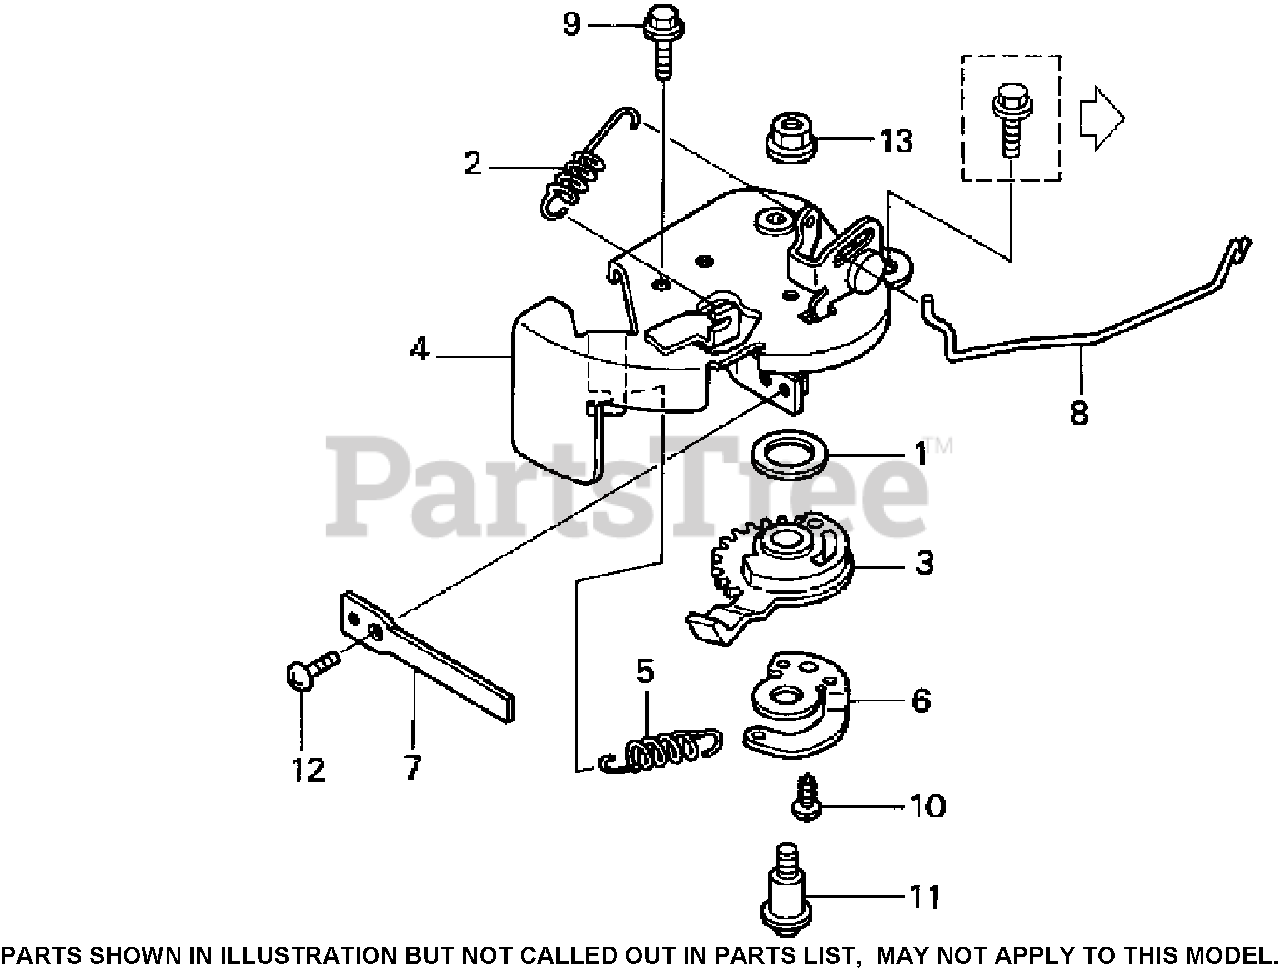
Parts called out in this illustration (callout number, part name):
1	SEAL-LEVER, CHOKE
2	SPRING-RETURN, CABLE
3	LEVER-CHOKE
4	BASE-CHOKE
5	SPRING-LEVER, CHOKE
6	HOOK-SPRING, CHOKE
7	PLATE-CHOKE
8	ROD-STOP
9	BOLT-FLANGE (6X16)
10	SCREW-TAPPING (4X8) (PO)
11	SCREW-PAN (5X19)
12	SCREW-PAN (4X8)
13	NUT-FLANGE (5MM)
